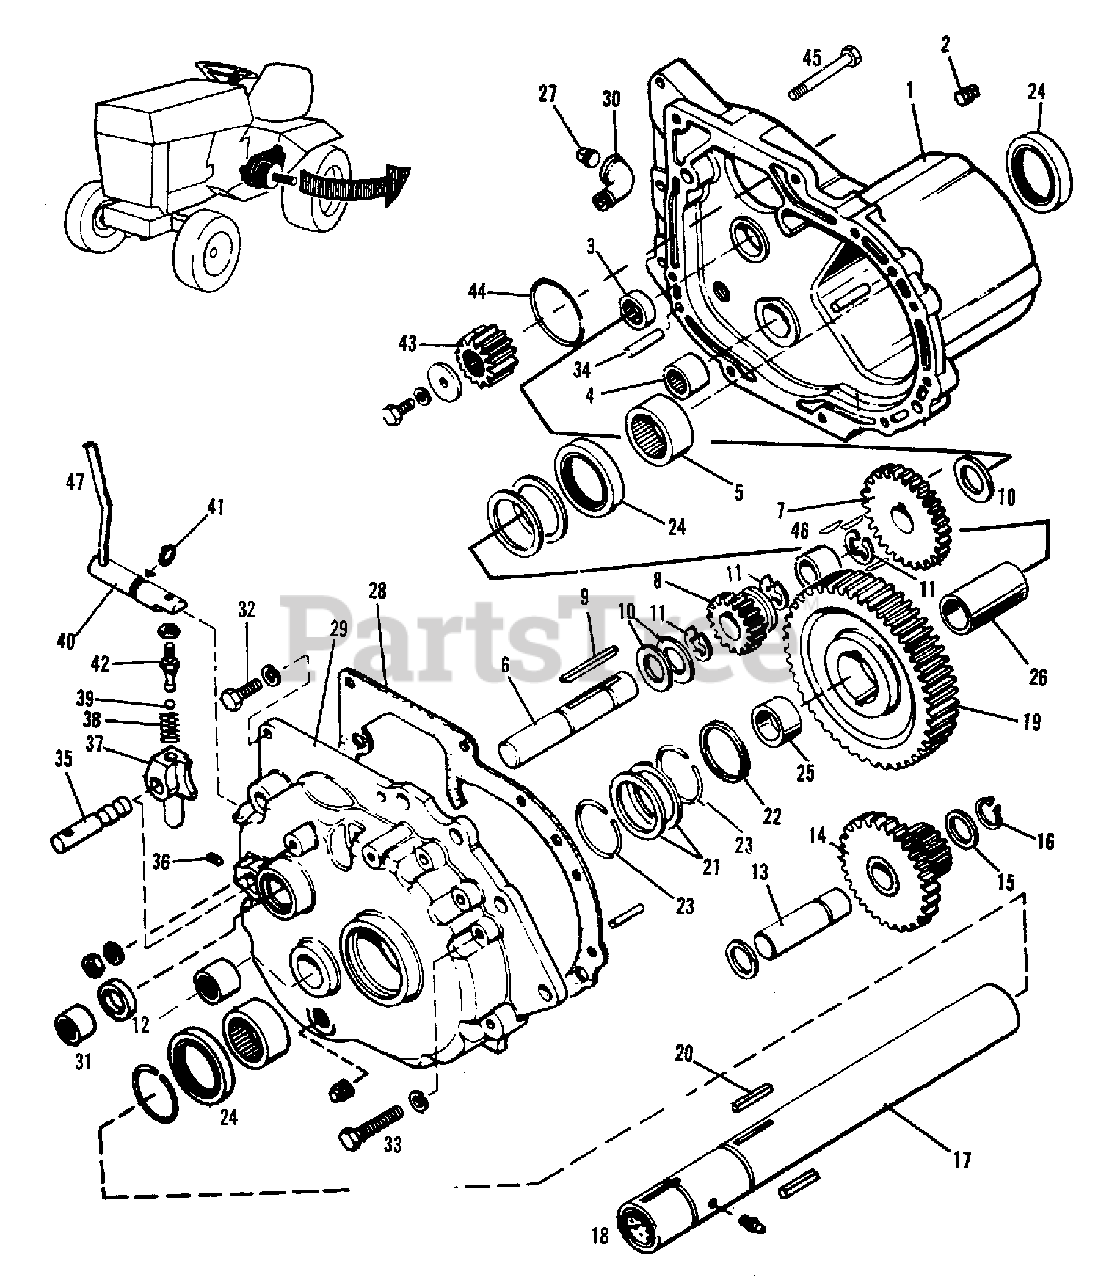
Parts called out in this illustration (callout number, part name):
1	CASE ASSEMBLY, Gear (Includes Items 3,4, & 5)
2	PLUG, Pipe, 1/4 Standard Square Head
3	BEARING, Needle
4	BEARING, Needle
5	BEARING, Needle
6	SHAFT, Brake
7	GEAR, 1st Intermediate
8	PINION, Sliding
11	RING, Retaining
12	SEAL, Oil
13	SHAFT, Intermediate
14	PINION & GEAR ASSEMBLY
16	RING, Retaining
17	TUBE ASSEMBLY, Axle
17	FITTING, Lube (Package Of 10)
19	GEAR, Drive
23	RING, Snap
25	SPACER, R.H., Axle
26	SPACER, L.H., Axle
27	PLUG, Pipe, 3/8 Standard Square Head
28	GASKET, Gear Case
29	COVER ASSEMBLY, Gear Case (Includes Items 4, 5, 31 & 34)
30	ELBOW, Street, 3/8 x 90 Degrees, Standard
31	BEARING, Needle
32	CAPSCREW, Hexagon Head, 5/16NC x 1
32	LOCKWASHER, 5/16, Regular
33	CAPSCREW, Hexagon Head, 5/16NC x 2
33	LOCKWASHER, 5/16, Regular
34	PIN, Roll
35	SHAFT, Shifter
36	SCREW, Set, Socket Head, 5/16NC x 1/2
37	FORK, Shift
39	BALL, Shift Lock
40	SHAFT ASSEMBLY, Shift
42	STEM, Shift
43	PINION, Motor Shaft
43	CAPSCREW, 5/16NF x 5/8
43	LOCKWASHER, 5/16
45	CAPSCREW, 7/16NC x 4 Gr8
45	LOCKWASHER, 7/16
45	NUT, 7/16NC
46	FLANGE ASSEMBLY, Drive
46	PIN, Dowel
47	HANDLE, Shift Control
